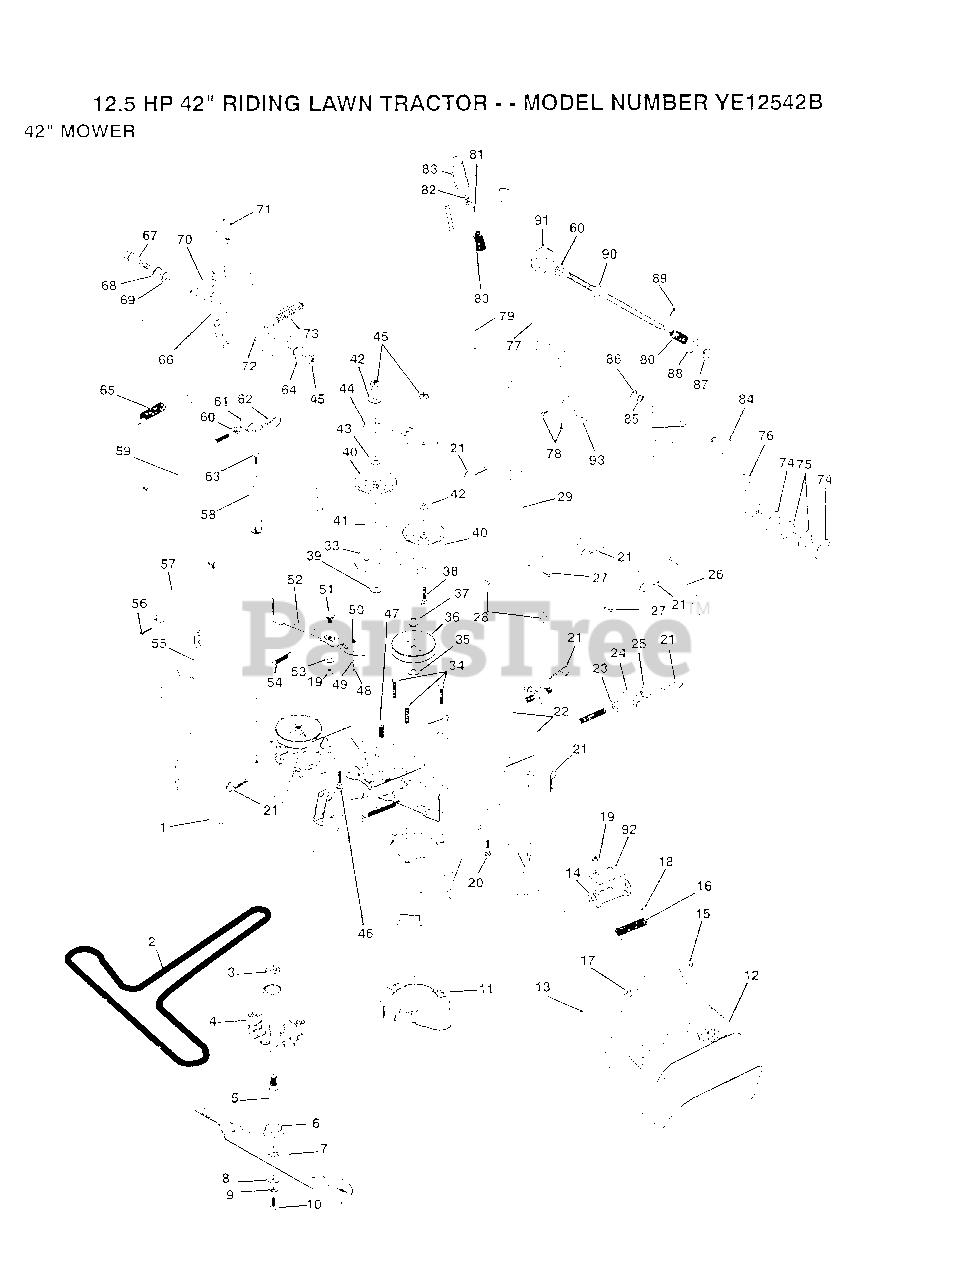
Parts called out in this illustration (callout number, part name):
2	BELT-V.92.4.MWR
3	BEARING
4	HSG ASM MANDREL
6	BEARING.BALL
8	WASHER BLADE
10	BLADE BOLT
12	DEFLECTOR.SHIELD
13	HINGE ROD
14	DEFLECTOR BRKT
15	NUT PUSH M
16	SPRING TORSION
17	WASHER
18	CAP-SLEEVE LT
20	BOLT
22	LINK.FRONT
23	NUT
24	TRUNION
25	NUT.LK.W/WSH.1/2.
26	LIFT LINK RH
27	"PIN,SPRING"
29	LINK LIFT LH
33	IDLER ARM
35	WASHER
38	BOLT
39	HARDENED WASHER
40	FLAT IDLER PULLEY
41	SPACER RETAINER
42	WASHER GT
43	RETAINER SPACER
44	IDLER ARM STIFF
46	BOLT CARRIAGE
47	XMAS TREE FASTNER
48	SHOULDER BOLT
50	LOCKNUT
52	BRAKE PAD ARM ASM
53	HARD SMALL WASHER
54	SPRING EXTENSION
55	PIVOT ROD
57	CLUTCH ROD SECOND
60	NUT
61	TRUNION
62	RETAINER M
63	SCREW LT
64	BUSHING
65	RETURN SPRING
66	CLUTCH ARM SECOND
67	SHOULDER BOLT
68	RING
69	WASHER
70	SPRING KEEPER
74	E-RING
75	WASHER
79	ROD ASS'Y LEVER
80	SPRING T
83	GRIP
84	TRUNION LT
85	WASHER
86	KLIP RING
87	NUT T
88	WASHER
90	ROD LIFT LT
92	STIFFENER BRKT
